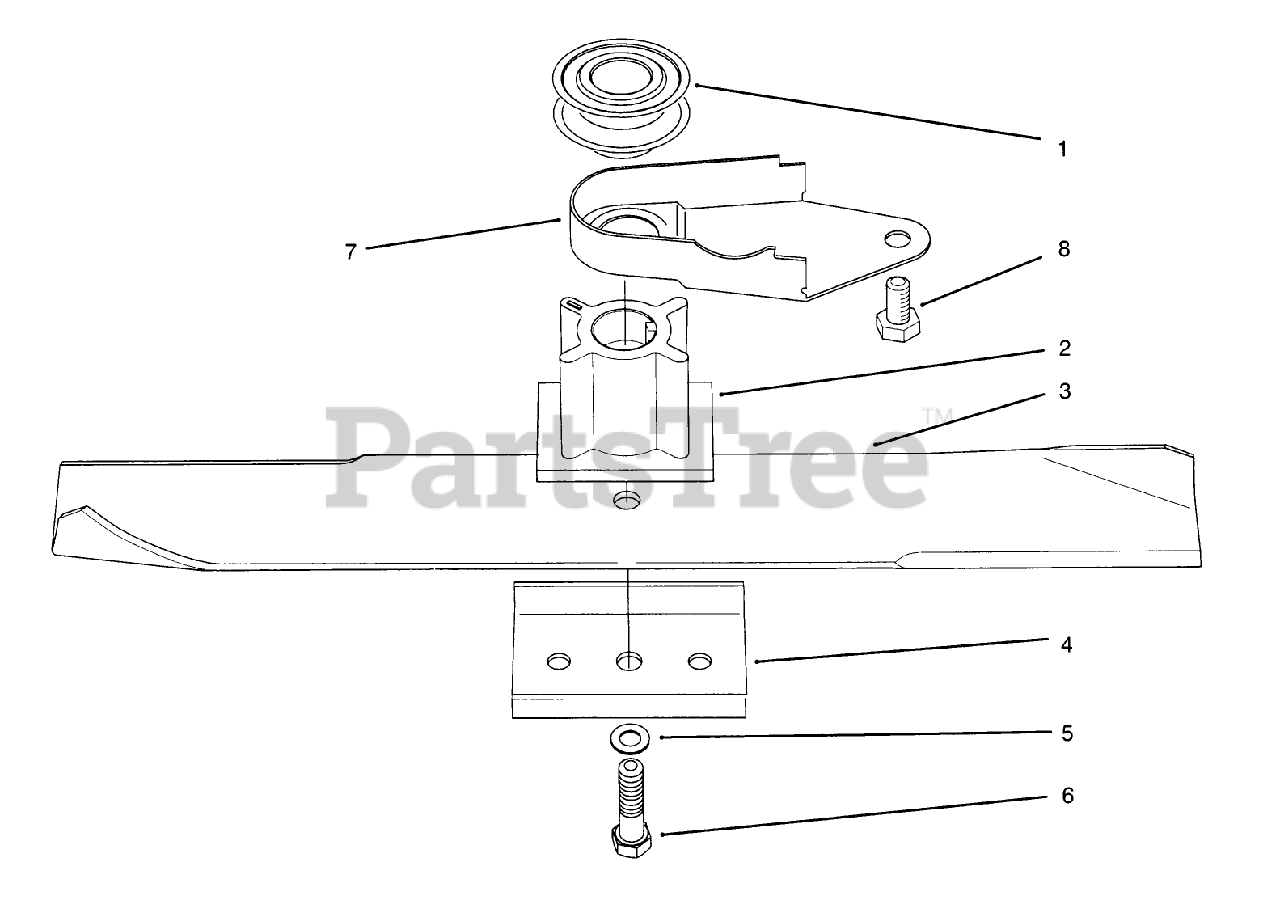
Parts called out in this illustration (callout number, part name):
1	PULLEY-DRIVE, ZONE START
5	WASHER-LOCK
6	BOLT-BLADE
7	COVER-GUIDE, BELT
